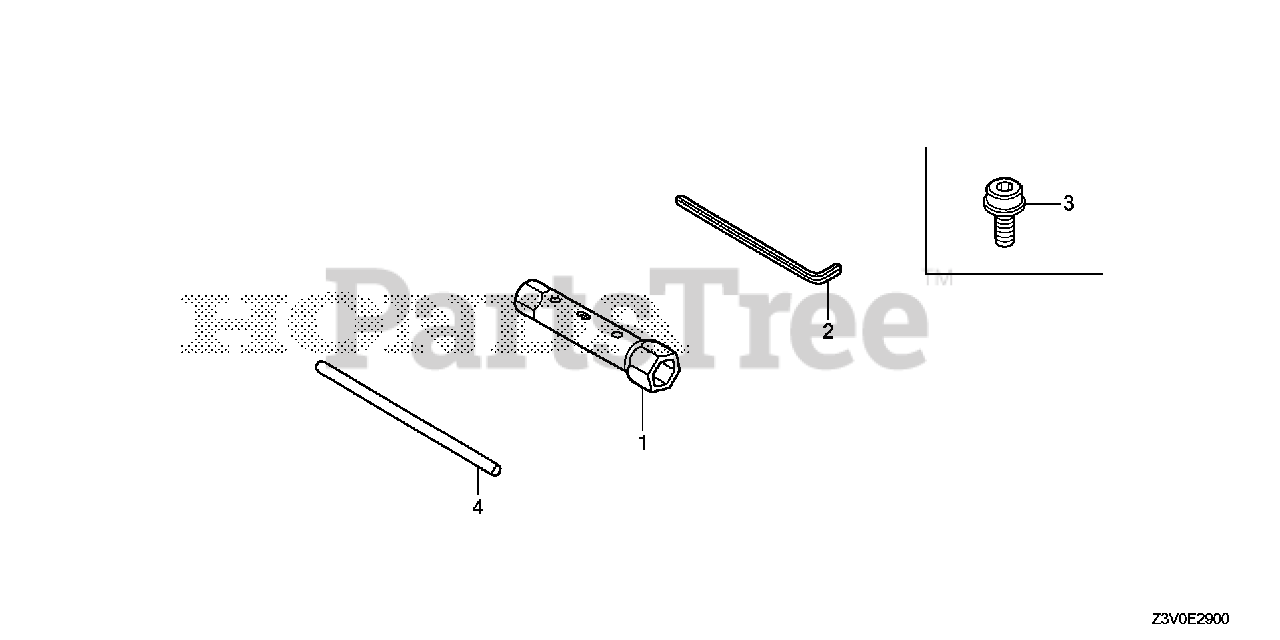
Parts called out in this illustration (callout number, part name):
1	WRENCH, PLUG (16X19)
2	WRENCH, HEX. (4MM)
3	BOLT, SOCKET (5X9)
4	BAR A, HANDLE
